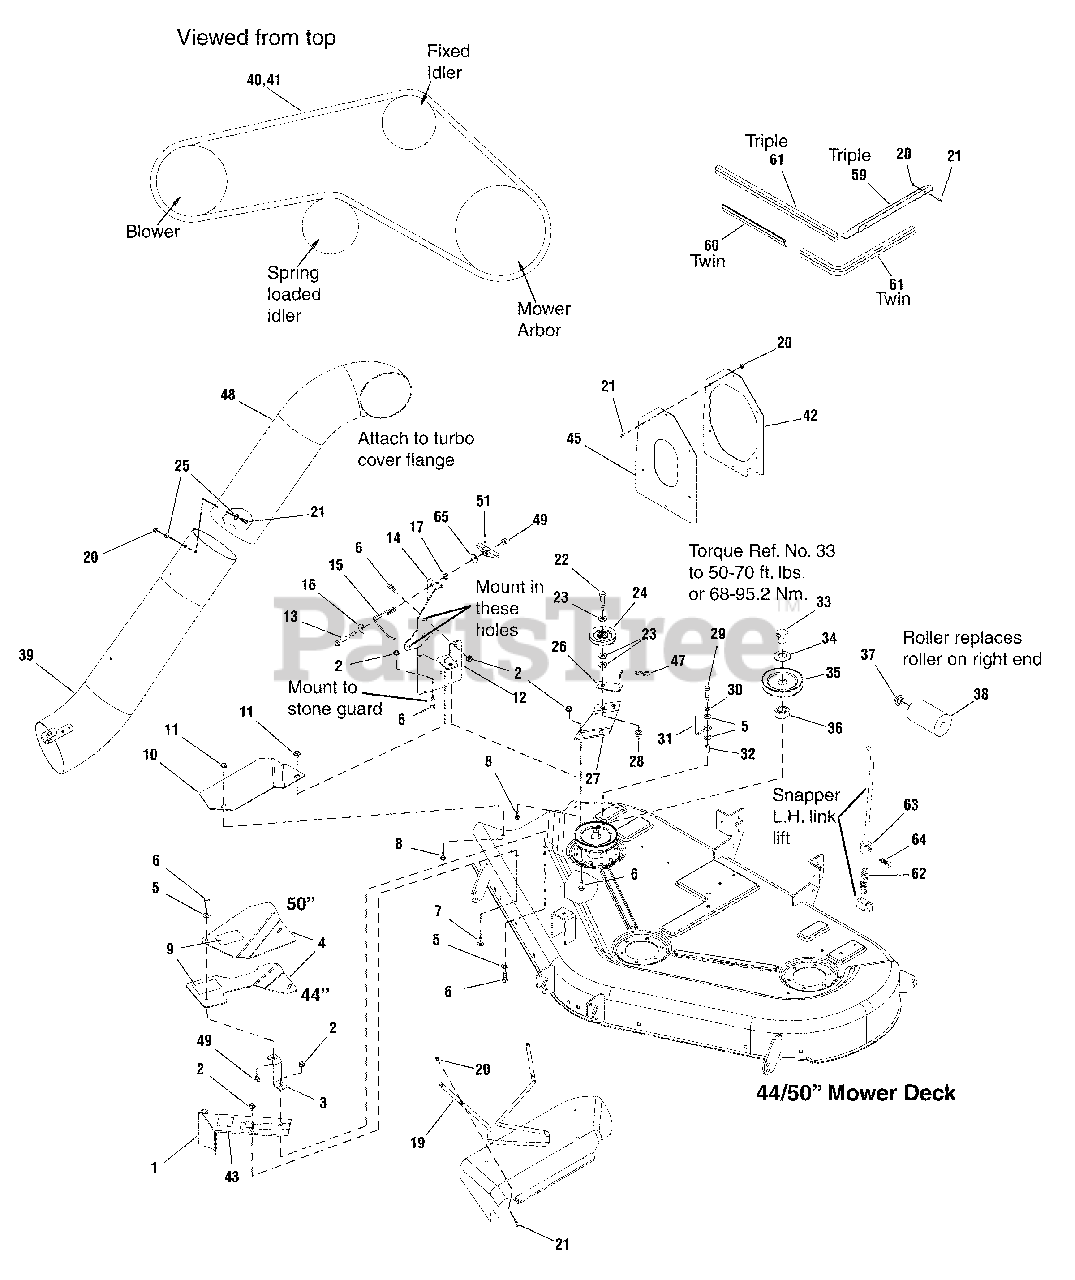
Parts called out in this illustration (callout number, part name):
1	PIVOT BRACKET ASSEMBLY
2	NUT, Hex Whiz Lock Flange, 5/16 - 18
3	SUPPORT, Belt Cover
4	COVER, Belt, 44"
4	COVER, Belt, 50"
5	WASHER, Flat, 5/16
6	CAPSCREW, Hex, 5/16 - 18 x 7/8
7	BOLT, Carriage, 5/16 - 18 x 3/4
8	BOLT, Carriage, 1/4 - 20 x 3/4
9	DECAL, Warning
10	COVER, Mower
11	NUT, Keps Conical, 1/4 - 20
12	BRACKET, Baffle
13	CAPSCREW, Hex, 5/16 - 18 x 2-1/2
14	BAFFLE, Turbo
15	SPRING, Latch
16	WASHER, 5/16
17	NUT, Keps Lock, 5/16 - 18
19	ROD, Deflector
20	NUT, ESNA Lock, 10 - 24
21	SCREW, Truss Phillips, 10 - 24 x 3/4
22	CAPSCREW, Hex, 3/8 - 16 x 2
23	WASHER, Flat, 3/8
24	PULLEY, Idler, 2-3/4
25	WASHER, Flat
26	BRACKET, "L"
27	BRACKET, "Z"
28	NUT, Whiz Lock Small, 3/8 - 16
29	CAPSCREW, Hex, 5/16 - 18 x 1-1/2
30	LOCKWASHER, 5/16
33	NUT, Short Sleeve
34	WASHER, Flat, 7/8
35	PULLEY, 4.3
36	HUB, Double, 5/8
37	NUT, Push
39	TUBE ASSEMBLY, Lower
40	V-BELT, 39.62
41	V-BELT, 37.9
42	SEAL, Flange
43	*DECAL, Patent
45	SEAL, Cover
47	PIN, Klik
48	TUBE, Upper
49	NUT, ESNA, 5/16 - 18
51	WINGNUT
59	PLATE, Deflector
60	SEAL, Rubber
61	SEAL, Rubber
62	SPRING, Compression
63	COLLAR, Locking
64	SCREW, Set, 5/16 - 19
65	WASHER, Spring Cup
